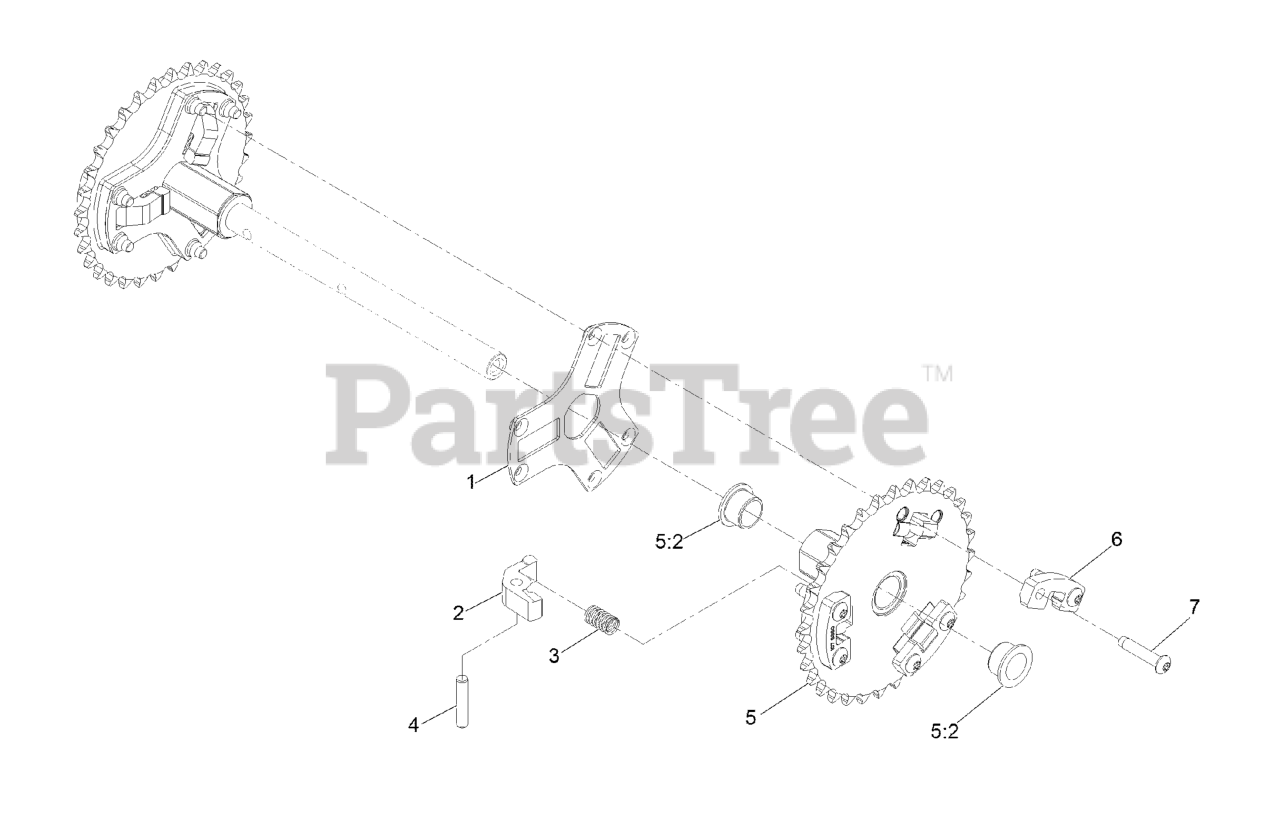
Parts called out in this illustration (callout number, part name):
1	RETAINER-PAWL, PIN
2	PAWL-CLUTCH
3	SPRING-COMPRESSION
4	PIN-DOWEL
5	32T SPROCKET ASM
5:2	BUSHING-FLANGE
6	SUPPORT-PAWL
7	SCREW-TTH, THREAD ROLLING
